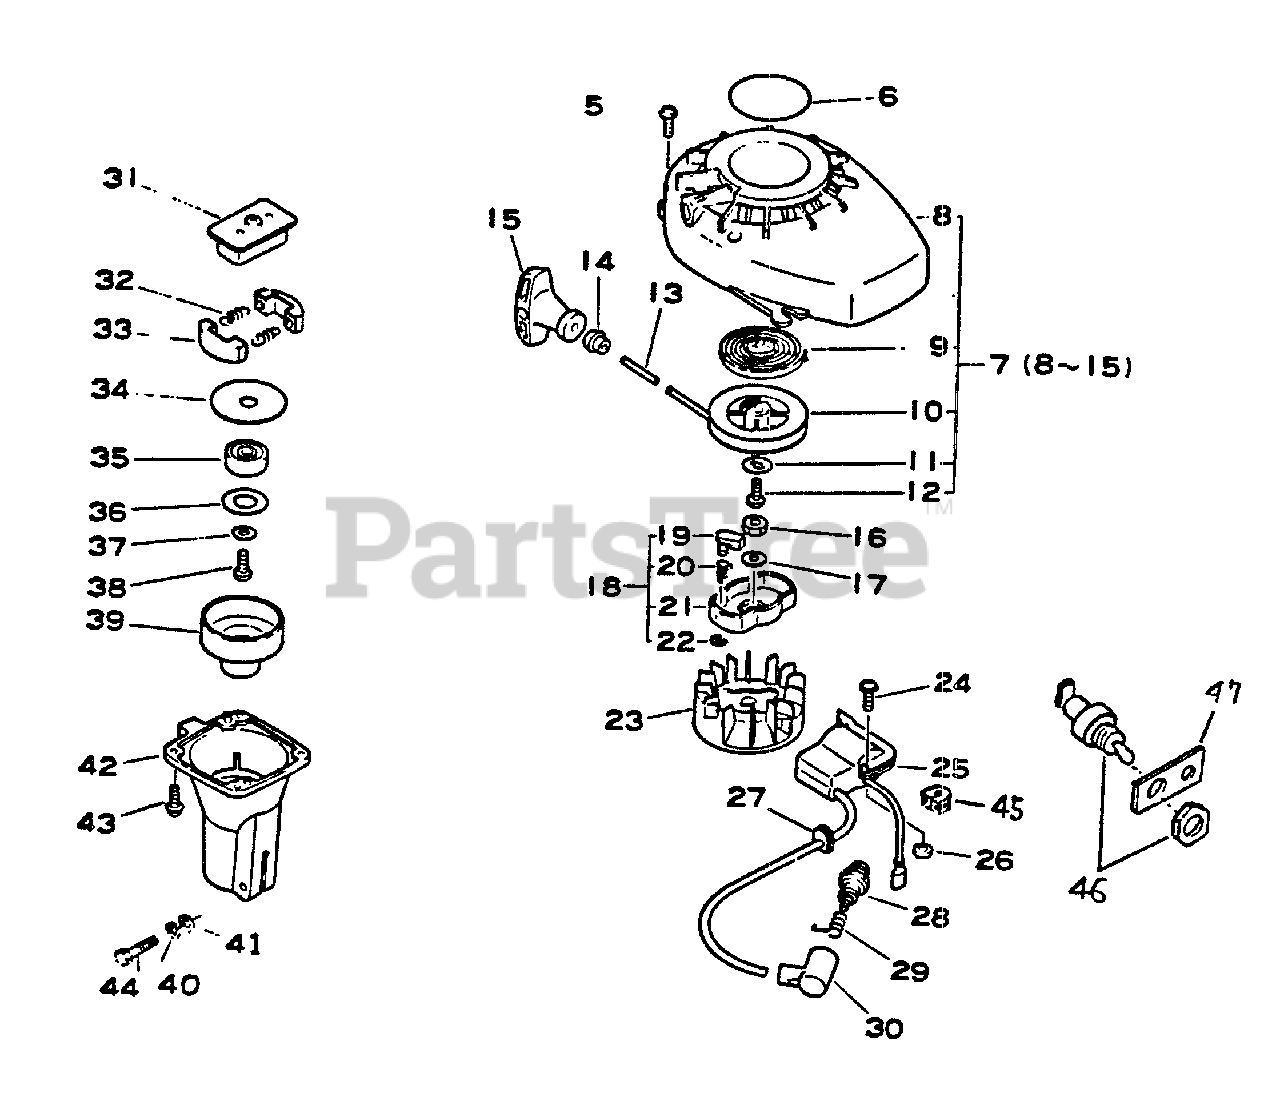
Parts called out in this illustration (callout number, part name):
5	SCREW - 4X15
7	STARTER ASSY
8	CASE, STARTER
9	SPRING, REWIND
10	REEL, ROPE
11	WASHER
13	ROPE, STARTER - 3X890
14	GUIDE, ROPE
15	GRIP, STARTER
17	WASHER - 8
18	STARTER PAWL ASSY
19	PAWL, STARTER
20	SPRING, RETURN
21	CATCHER, PAWL
22	RING, RETAINING - 6
23	FLYWHEEL
24	SCREW - 4X22
25	COIL, IGNITION
28	SPARK PLUG -- CJ-8Y
29	TERMINAL, SPARK PLUG CAP
30	CAP, SPARK PLUG
31	HUB, CLUTCH
32	SPRING, CLUTCH
33	SHOE, CLUTCH
34	PLATE, CLUTCH
35	BEARING, BALL - 6000
36	WASHER, CLUTCH
37	WASHER - 6
38	SCREW - 6X12
39	DRUM, CLUTCH
40	LOCKWASHER - 5
41	WASHER - 5
42	CASE, CLUTCH
43	SCREW - 4X14
44	BOLT - 5X25
46	LEAD
50	COIL, IGNITION
